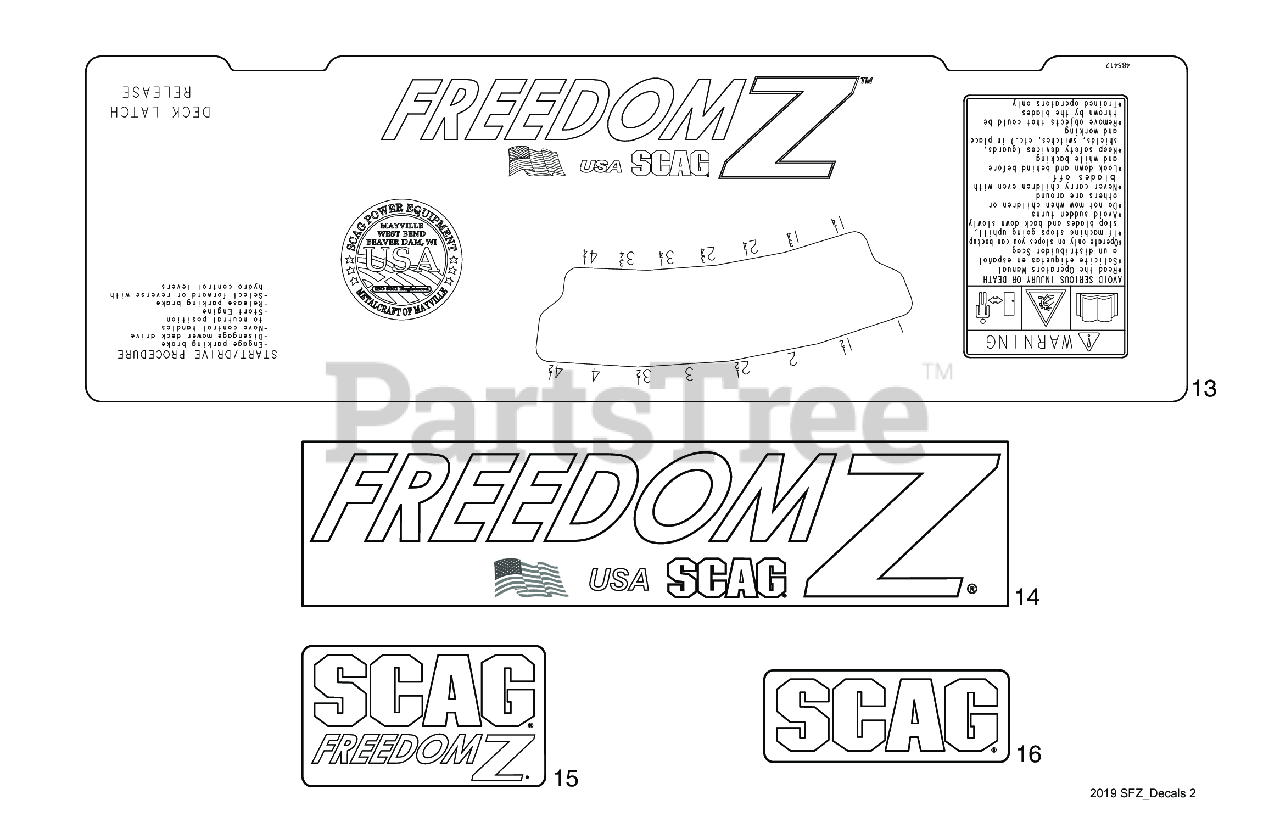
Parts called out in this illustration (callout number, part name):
13	Decal, Cutting Height
14	Decal, Freedom Z (Fuel Tank)
15	Decal, Scag Freedom Z (Fuel Tank)
16	Decal, Scag - Fuel Tank
